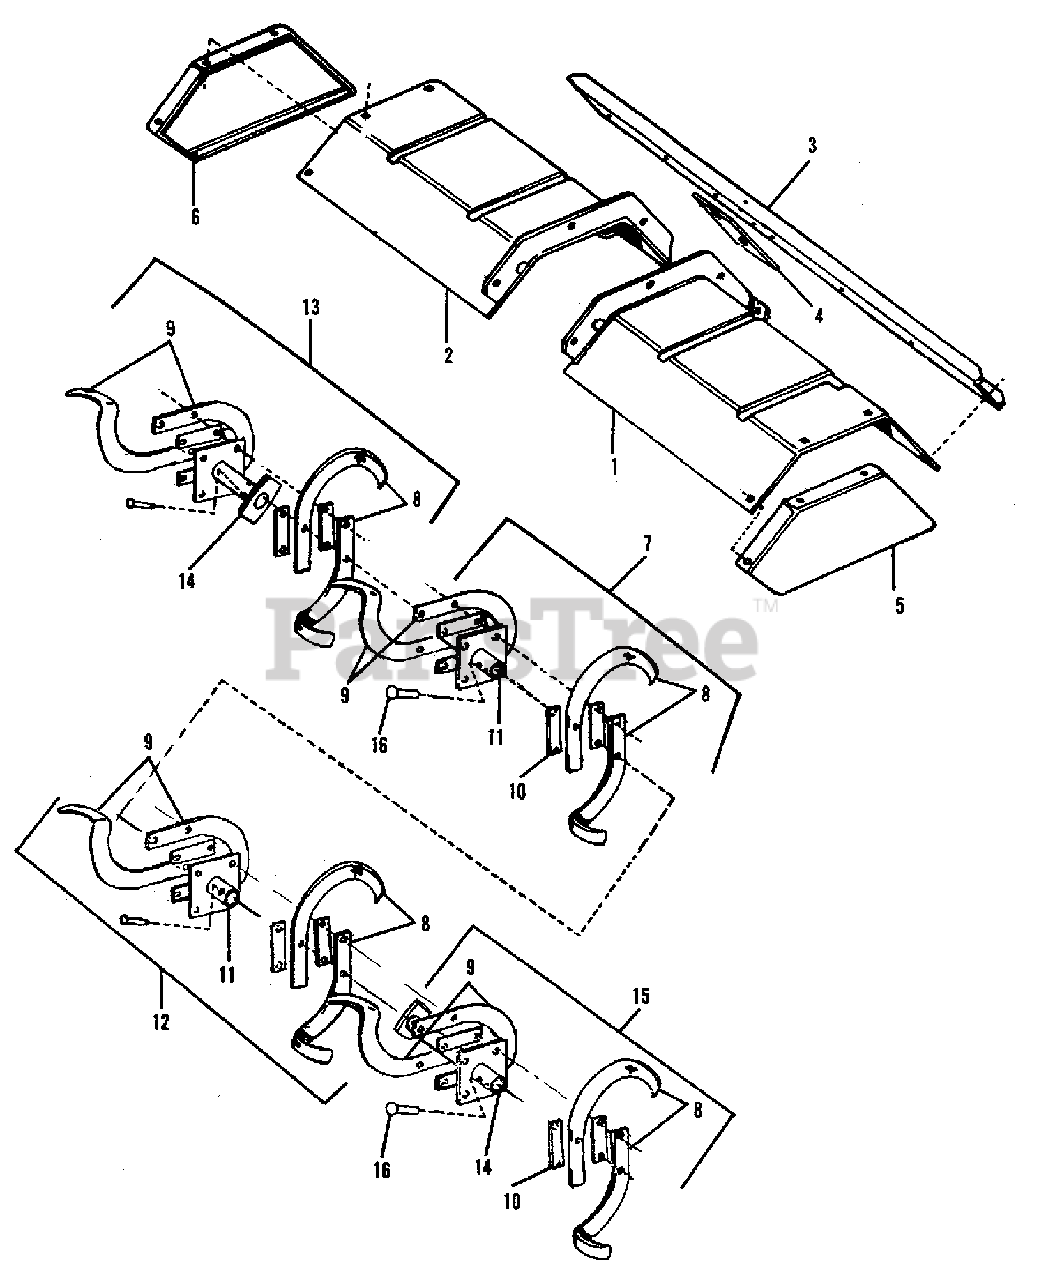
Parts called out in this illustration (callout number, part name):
1	DEFLECTOR ASSEMBLY, L.H.
1	CAPSCREW, Hexagon, 3/8NC x 1
1	WASHER, Lock, 3/8
2	DEFLECTOR ASSEMBLY, R.H.
2	CAPSCREW, Hexagon, 3/8NC x 1
2	WASHER, Lock, 3/8
3	CHANNEL, Reinforcing
3	WASHER, Lock, 3/8
3	NUT, Hexagon, 3/8NC
3	CARRIAGE BOLT, 5/16NC x 3/4
3	WASHER, Lock, 5/16
3	NUT, Hexagon, 5/16NC
3	SCREW, Hexagon Head, 3/8NC x 5/8 lg.
5	END, L.H., Plate Deflector
5	CARRIAGE BOLT, Short, 5/16NC x 1/2
5	WASHER, Lock, 5/16
5	NUT, Hexagon, 5/16NC
6	END, R.H., Plate Deflector
6	CARRIAGE BOLT, Short, 5/16NC x 1/2
6	WASHER, Lock, 5/16
6	NUT, Hexagon, 5/16NC
7	BLADE ASSEMBLY, R.H. Inner Tine
8	BLADE, L.H., Tine
9	BLADE, R.H., Tine
10	SPACER, 1/4 x 1 x 4
11	HUB ASSEMBLY, Attach
11	CAPSCREW, Hexagon, 7/16NC x 2
11	LOCKNUT, Hexagon, 7/16NC
12	BLADE ASSEMBLY, L.H. Inner Tine
13	BLADE ASSEMBLY, R.H. Outer Tine
14	PLATE ASSEMBLY, Tine
14	CAPSCREW, Hexagon, 7/16NC x 2
14	LOCKNUT, Hexagon, 7/16NC
15	BLADE ASSEMBLY, Outer Tine
16	PIN, Tine Shaft
16	PIN, Cotter, 1/8 x 3/4
